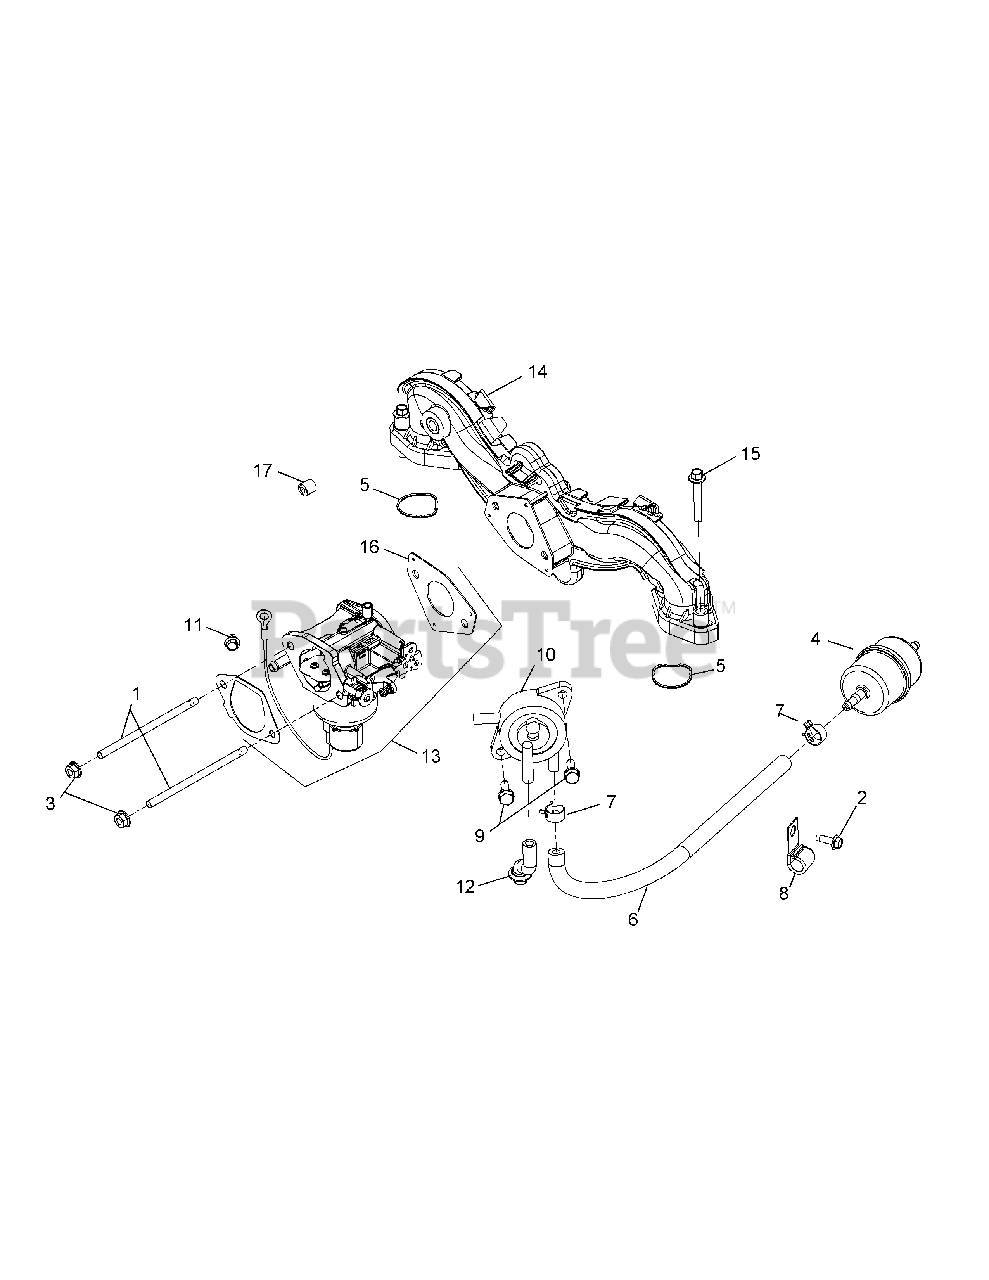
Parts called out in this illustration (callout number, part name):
2	Thread Forming Screw
3	Flange Nut, M6 x 1.0
4	Fuel Filter
5	Intake Port O-Ring
6	Fuel Line, 24"
7	Spring Hose Clamp
9	Tap Screw, M6 x 1.7 x 18
11	Thread Forming Screw
12	Pulse Pump Hose
13	Carburator Kit
14	Intake Manifold Kit
15	Flange Screw, M6 x 1.0 x 40
16	Carburetor Gasket
17	Pipe Plug, 1/8
